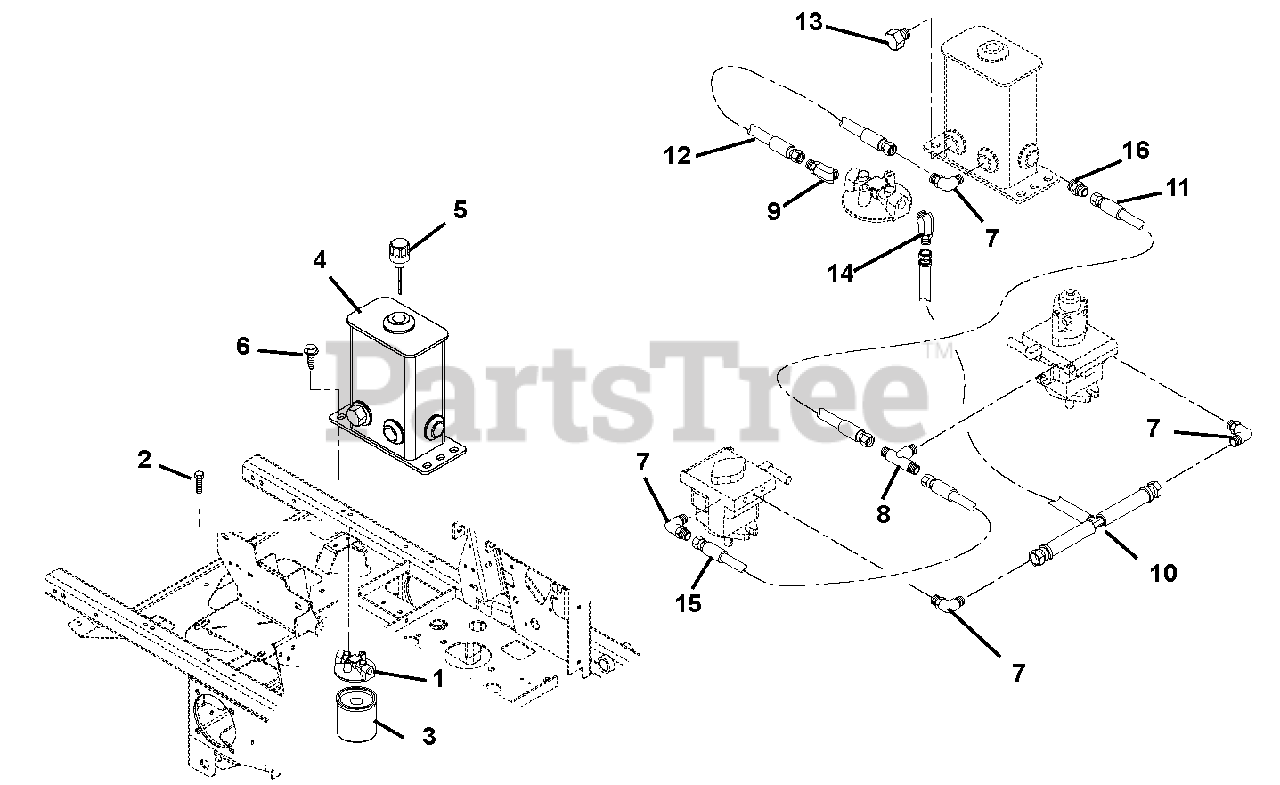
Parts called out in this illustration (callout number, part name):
1	Head, Filter (Serial Numbers 000101 and 000400)
2	Bolt, Hex .25-20 x .50 Grade 5 Epoxy
3	Oil Filter
4	Tank, Hydraulic (SN 000101 - 002499)
5	Hydraulic Tank Dipstick
6	Screw, Tapping .38-16 x .75 Hex Washer Head
7	Fitting, Hydraulic 90 Degree Elbow (SN 000500 - 002499)
8	Fitting, Hydraulic Tee M80-M80-M80
9	Fitting, Hydraulic 45° M80-M120 (SN 000101 - 000400)
10	Hose, Tee Assembly, .50
11	Hose, Hydraulic
12	Hose, Hydraulic (SN 000101 - 000400)
13	Plug, Hex, .75-16 O-Ring
14	Fitting, Hydraulic 45° M80-M120 SN 000101 - 000400)
15	Hose, Hydraulic
16	Adapter, Face Seal 8 x 8 .50 O-Ring 8 F5OLO-Steel (SN 002500 and up)
